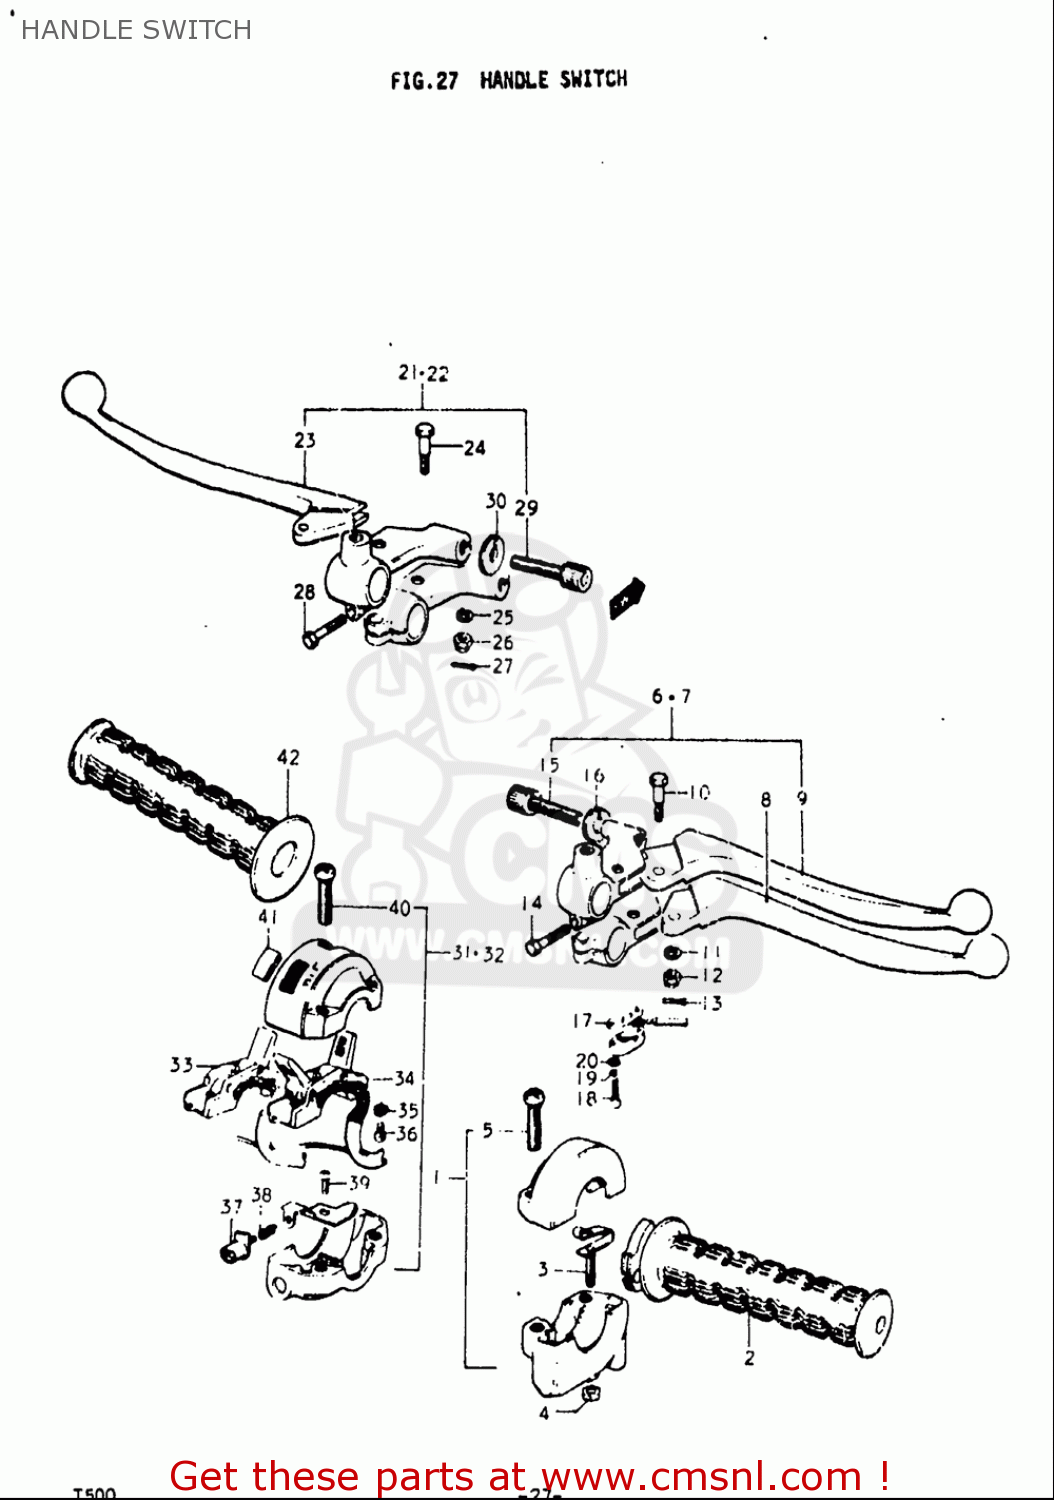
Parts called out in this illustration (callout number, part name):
2	GRIP,THROTTLE
3	ADJUSTER, THROTTLE
4	NUT
5	SCREW
8	LEVER,BRAKE
9	LEVER,BRAKE
10	WASHER,LOCK
12	NUT,LEVER FITTNG
13	PIN 16X20
14	BOLT
15	ADJUSTER,CABLE
16	NUT,CABLE ADJUSTER
18	SCREW
19	WASHER,LOCK
20	WASHER
23	LEVER,CLUTCH
24	BOLT,LEVER PIVOT
25	WASHER,LOCK
26	NUT,LEVER FITTNG
27	PIN 16X20
28	BOLT
29	ADJUSTER,CABLE
30	NUT,CABLE ADJUSTER
35	WASHER,LOCK
36	SCREW
37	BUTTON, HORN
39	SCREW
40	SCREW
42	GRIP
